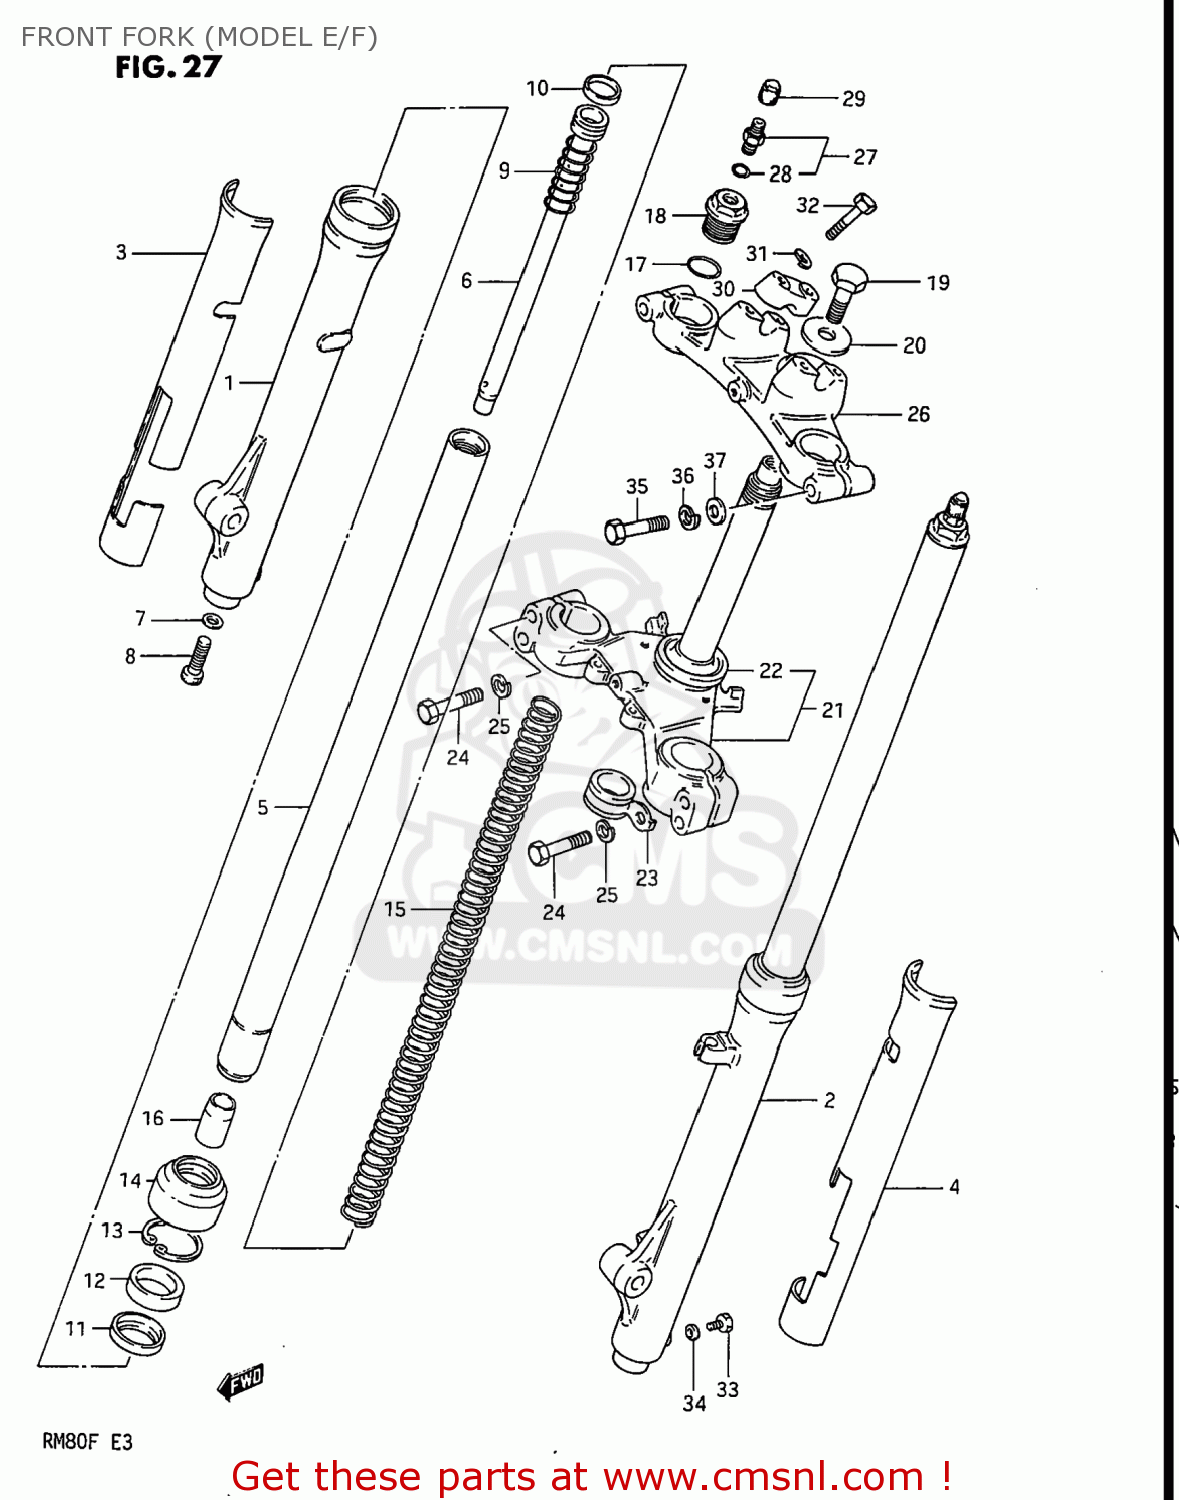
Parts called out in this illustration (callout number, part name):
1	TUBE,OUTER,RIGHT
2	TUBE,OUTER,LEFT
3	PROTECTOR,FRONT FORK,RIGHT
4	PROTECTOR,FRONT FORK,LEFT
5	TUBE,INNER
6	CYLINDER,FRONT FORK
7	GASKET (NAS)
8	BOLT(8X27)
9	SPRING,REBOUND
10	RING,PISTON
11	SPACER,FORK OIL SEAL
12	SEAL,OIL
13	CIRCLIP,FORK OIL SEAL
14	SEAL,DUST
15	SPRING,FRONT FORK
16	PIECE,OIL LOCK
17	O RING
18	BOLT,FORK INNER TUBE
19	BOLT,STEERING STEM HEAD
20	WASHER,STEERING STEM
21	STEM,STEERING
22	RACE,STEERING OUTER LWR
23	GUIDE,CABLE
24	BOLT,FORK INNER TUBE F
25	LOCK WASHER
26	HEAD,STEERING STEM
27	VALVE,AIR
28	O-RING (D:3.8 ID:19)
29	CAP
30	HOLDER,HANDLEBAR
31	LOCK WASHER
32	BOLT
33	BOLT
34	GASKET,DRAIN,PLUG (NAS)
35	BOLT 8X40
36	LOCK WASHER
37	WASHER
